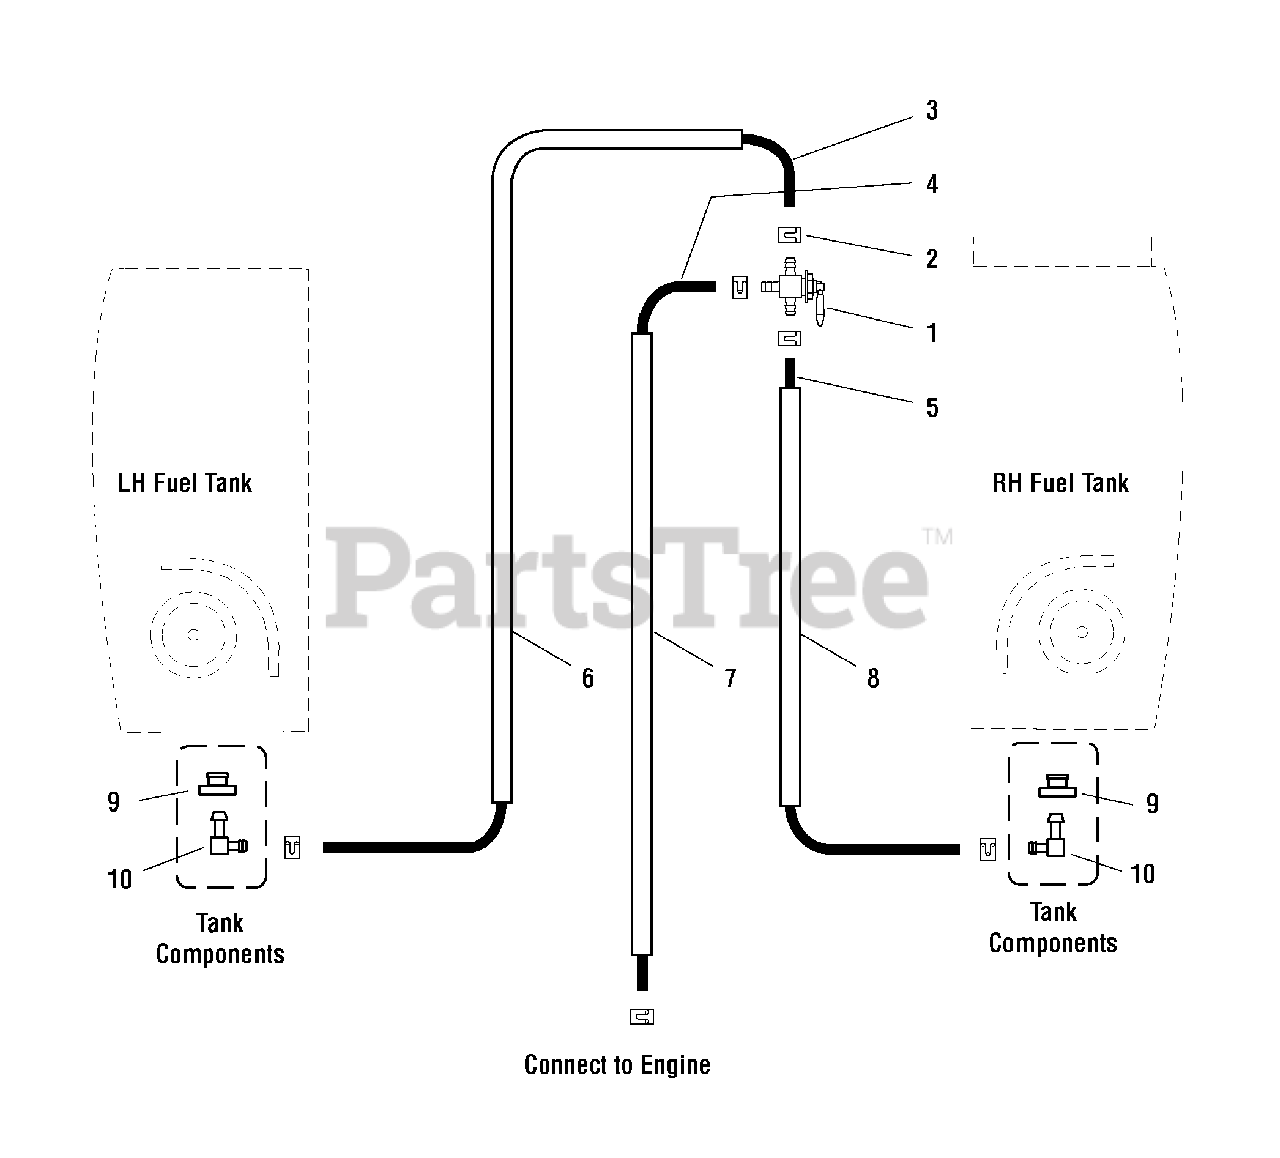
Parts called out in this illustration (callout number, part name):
1	VALVE, Fuel Shut Off
2	CLAMP, Hose
6	WIRE LOOM, 51"
7	WIRE LOOM, 33"
8	WIRE LOOM, 24"
9	RUBBER BUSHING
10	ELBOW FITTING
